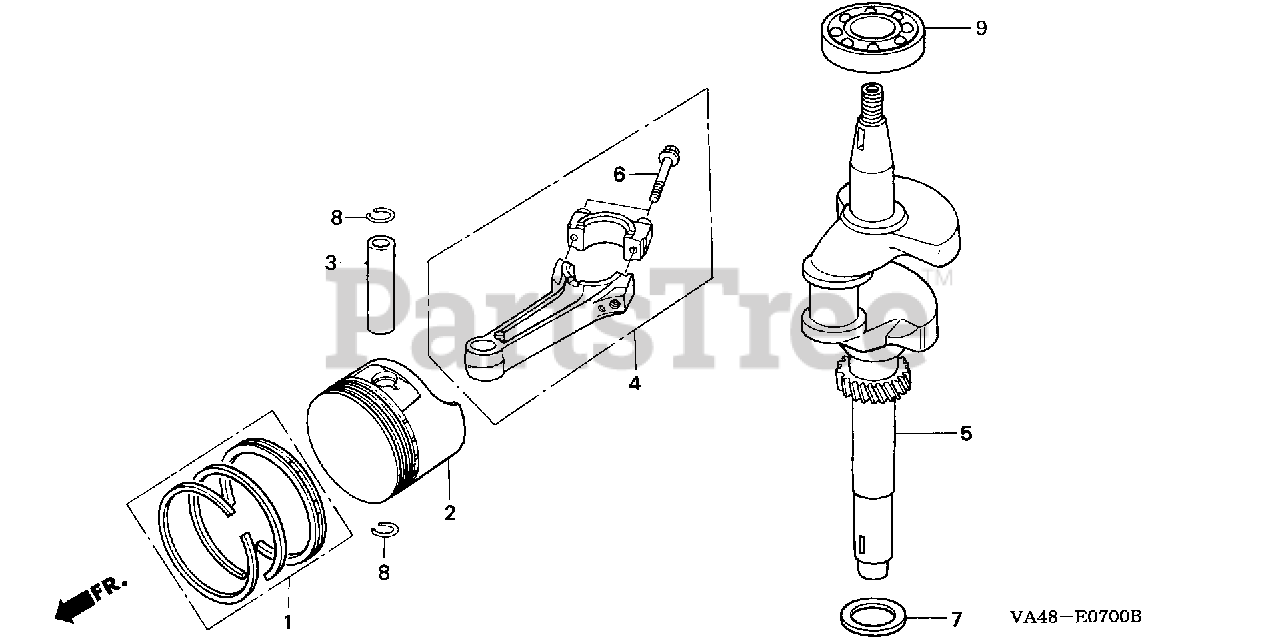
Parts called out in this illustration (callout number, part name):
1	RING SET, PISTON (STD) (GOETZE)
1	RING SET, PISTON (STD) (FEDERAL MOGUL)
1	RING SET, PISTON (STD) (NIPPON)
1	RING SET, PISTON (0.25) (FEDERAL MOGUL) Use from Engine SN 7666484.
1	RING SET, PISTON (OS 0.25) (NIPPON)
1	RING SET, PISTON (OS 0.25) (TEIKOKU) Use up to Engine SN 7666483.
1	RING SET, PISTON (0.50) (FEDERAL MOGUL) Use from Engine SN 7666484.
1	RING SET, PISTON (OS 0.50) (TEIKOKU)
1	RING SET, PISTON (0.75) (GOETZE) Use up to Engine SN 7666483.
1	RING SET, PISTON (OS 0.75) (FEDERAL MOGUL)
1	RING SET, PISTON (OS 0.75) (NIPPON)
2	PISTON (STD)
2	PISTON (OS 0.25) Use up to Engine SN 7666483.
2	PISTON (0.50)
2	PISTON (OS 0.75)
3	PIN, PISTON
4	ROD ASSY., CONNECTING
4	ROD ASSY., CONNECTING (US 0.25) Use from Engine SN 2250473.
5	CRANKSHAFT
6	BOLT, CONNECTING ROD
8	CLIP, PISTON PIN (13MM)
9	BEARING, RADIAL BALL (62/22)
